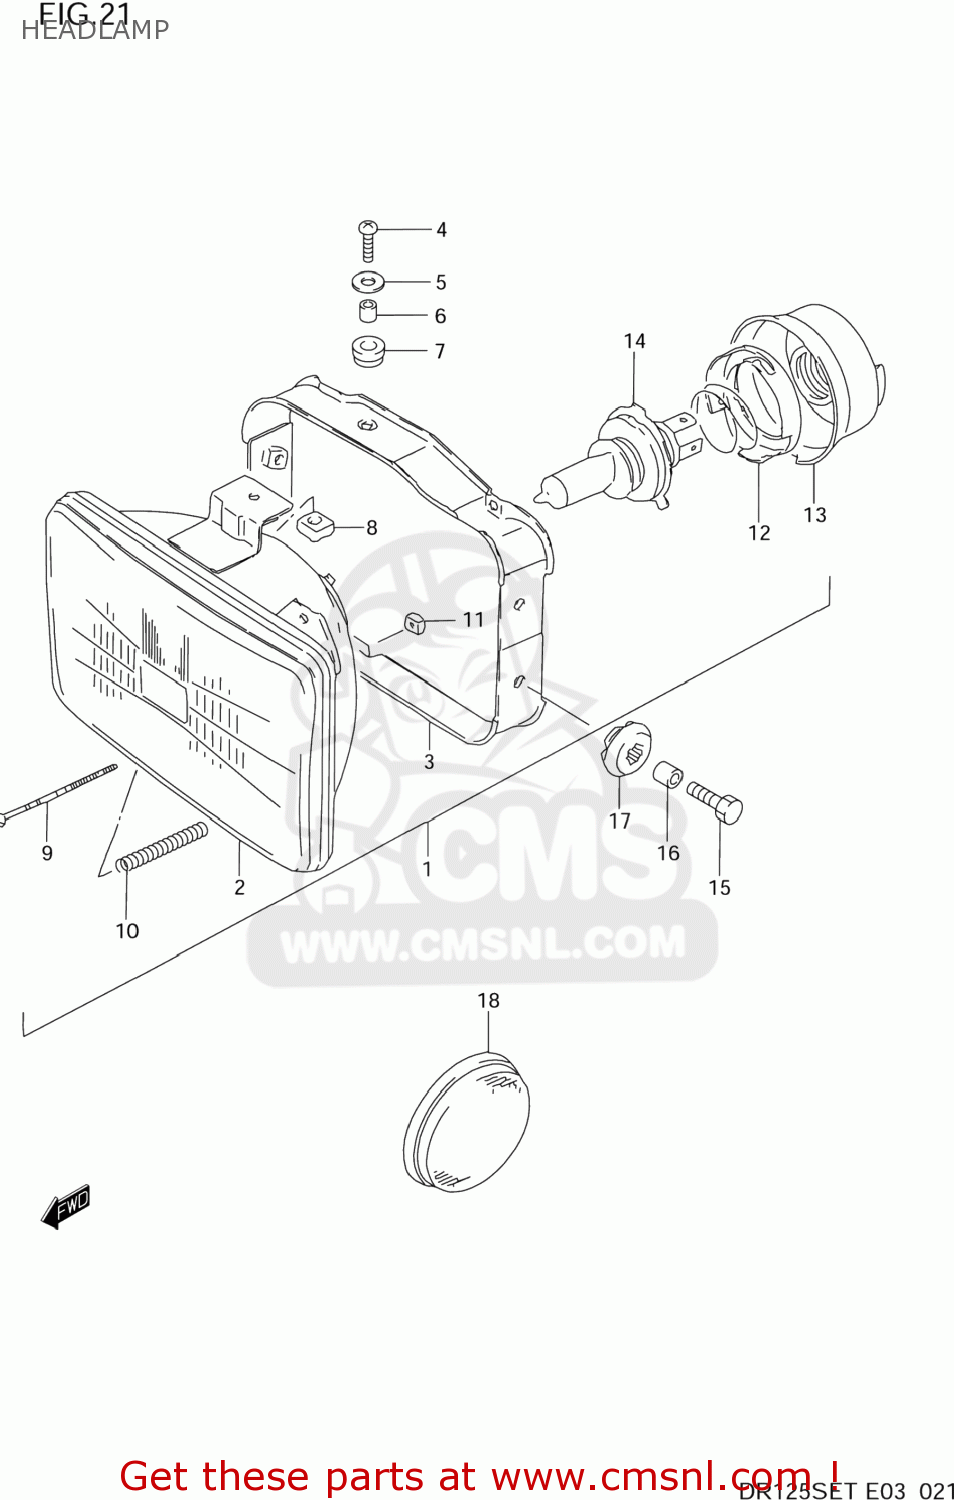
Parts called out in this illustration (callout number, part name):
1	HEADLAMP ASSEMBLY
2	LAMP UNIT
3	HOUSING
4	SCREW
5	WASHER
6	SPACER
7	CUSHION
8	NUT
9	SCREW
10	SPRING
11	NUT
12	HOLDER,BULB
13	COVER,SOCKET
14	BULB(12V60/55W,H4)
15	BOLT(6X20)
16	SPACER (6.1X9X9)
17	CUSHION
18	REFLECTOR,REFLEX FR
